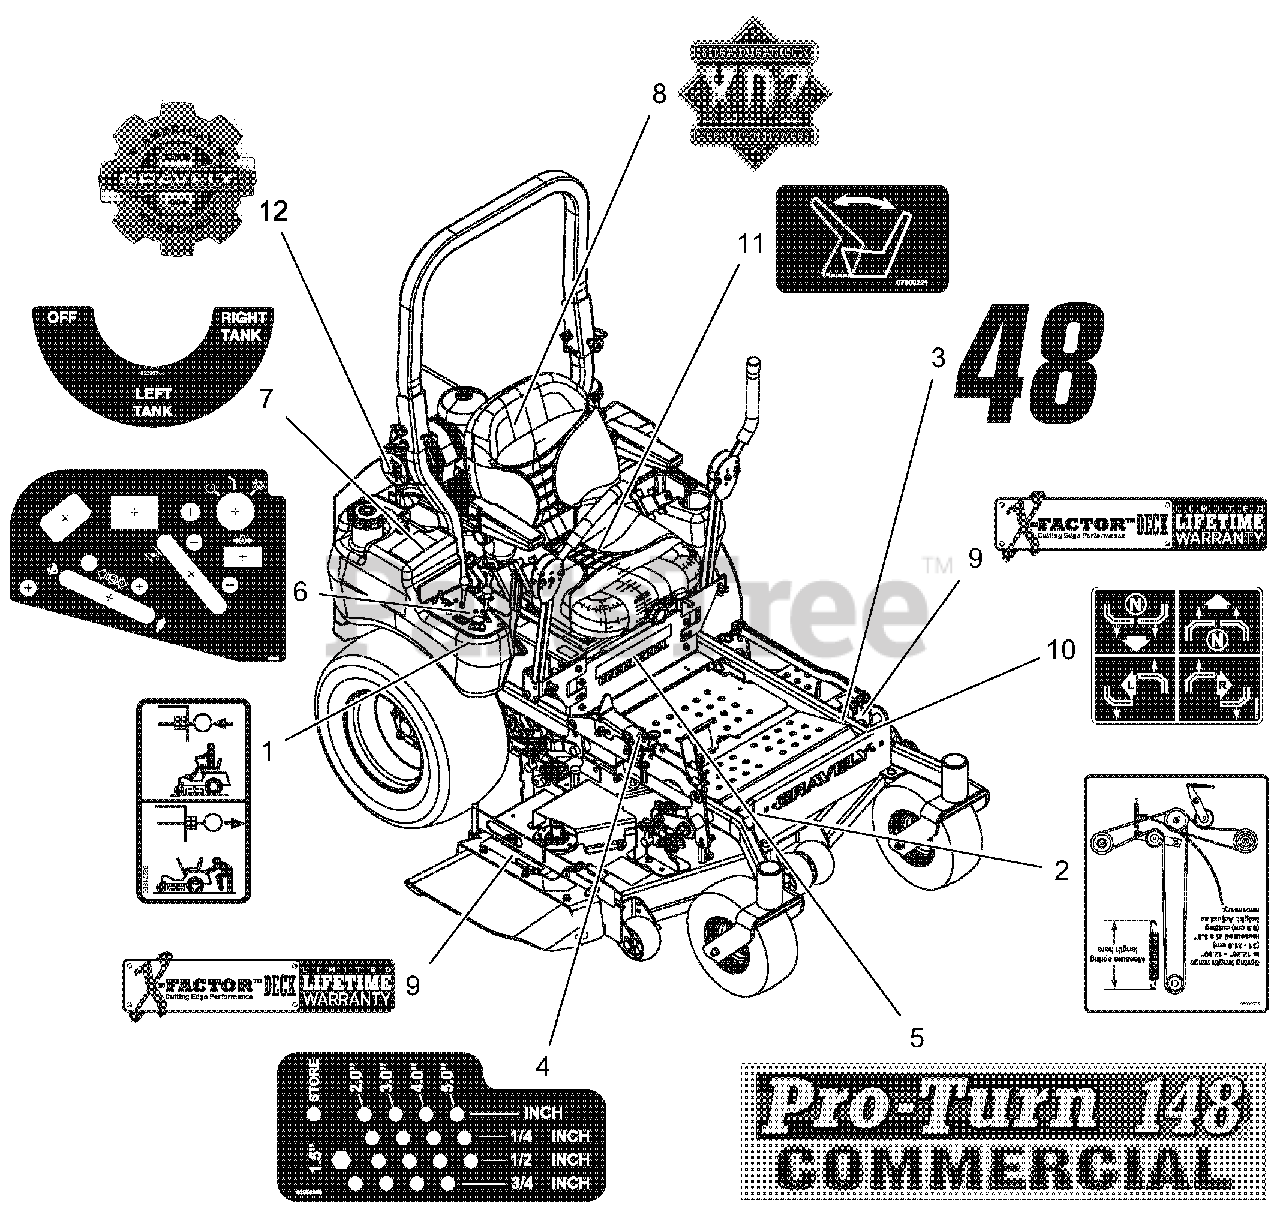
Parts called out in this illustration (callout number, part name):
1	DECAL, TRANSMISSION DISCONNECT
2	DECAL, BELT ROUTING
3	DECAL, 48"
4	DECAL, HEIGHT OF CUT
5	DECAL, PRO-TURN 148
6	DECAL, CONTROL PANEL
7	DECAL, FUEL VALVE
8	DECAL, XDZ
9	DECAL, X-FACTOR DECK
10	DECAL, INSTRUCTIONAL - STEERING
11	DECAL, SEAT RELEASE
12	DECAL, GRAVELY HERITAGE-LARGE
